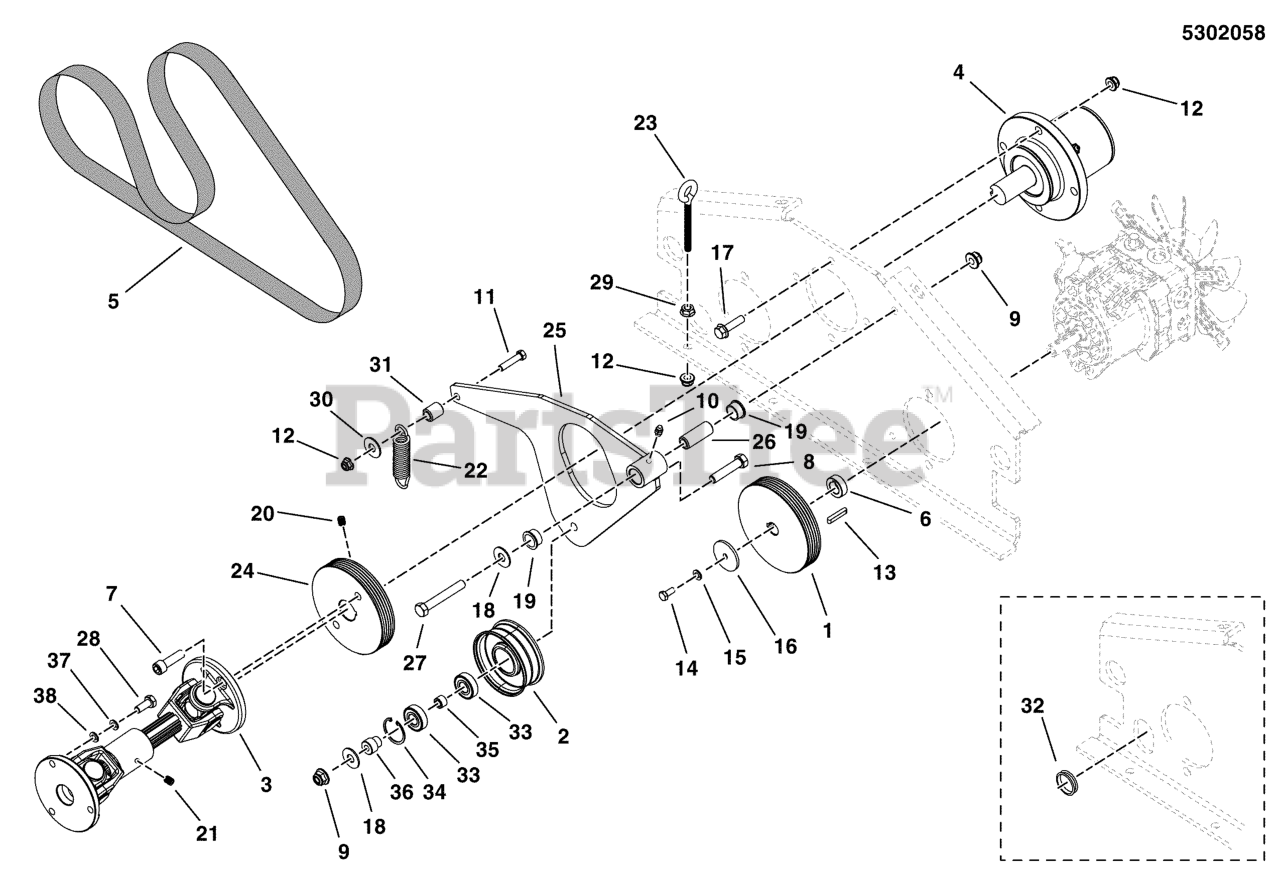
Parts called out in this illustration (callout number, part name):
1	PULLEY, POLY V "K" SECTION 5K4.5 X 15MM
2	ASSM, PULLEY, FLAT BACKSIDE IDLER - 2.75
3	DRIVE SHAFT ASM, IS2500Z
4	ASSM, CARRIER BEARING
5	BELT, POLYRIB, 49.75, 5 RIB
6	BUSHING, 15MM X 25MM X 8.6MM - KEYED
7	CAPSCREW-HEX HD 3/8-16X1.000 G5 BLK
8	BOLT, 3/8-16 X 1-3/4" GD5 CZ
9	NUT, 3/8-16 HEX NYLOCK FLANGE
10	GREASE FITTING, 1/4-28 STRAIGHT
11	BOLT, 5/16-18 X 1-1/4 GD5 YZ
12	NUT, 5/16-18 HEX NYLOCK FLANGE
13	KEY, 5MM SQ. W/ RADIUS
14	CAPSCREW-HEX HEAD M6-1.0X 14MM W/PATCH
15	WASHER, 1/4 LOCK
16	WASHER, .265 X 1.50 X .109, YZ
17	BOLT, 5/16-18 X 1 1/4 FLANGE
18	WASHER, 3/8 USS
19	BUSHING-0.628IDX0.751ODX0.400LG PWDR MTL
20	SET SCREW, 3/8-16 X 1/2 KNURLED, W/PATC
21	SET SCREW, 1/4-28 X 1/4
22	SPRING, SWIVEL HOOK, .93"OD X 4.020" LG
23	EYE BOLT, 5/16-18 X 4", 2-3/4 THRD CZ
24	PULLEY, POLY V "K" SECTION 5K4.25 X 1"
25	WELD, IDLER ARM - BLK
26	SPACER, .38 X .625 X 1.62, YZ
27	BOLT, 3/8-16 X 2-1/2" GD5 CZ
28	BOLT, M8-1.25 X 20MM GD8.8
29	NUT, 5/16-18 HEX SERRATED FLANGE (SMALL)
30	WASHER, 5/16 USS
31	SPACER, .38 X .50 X .27
32	GROMMET, 1-1/2" ID FOR 1/4" METAL
33	BEARING, BALL 11/16X1-9/16X15/32
34	SNAP RING, INTERNAL
35	INSERT, BEARING, 17MM X 12MM L
36	SPACER, SHOULDER
37	WASHER, 5/16 LOCK CZ
38	WASHER, 5/16" SAE
